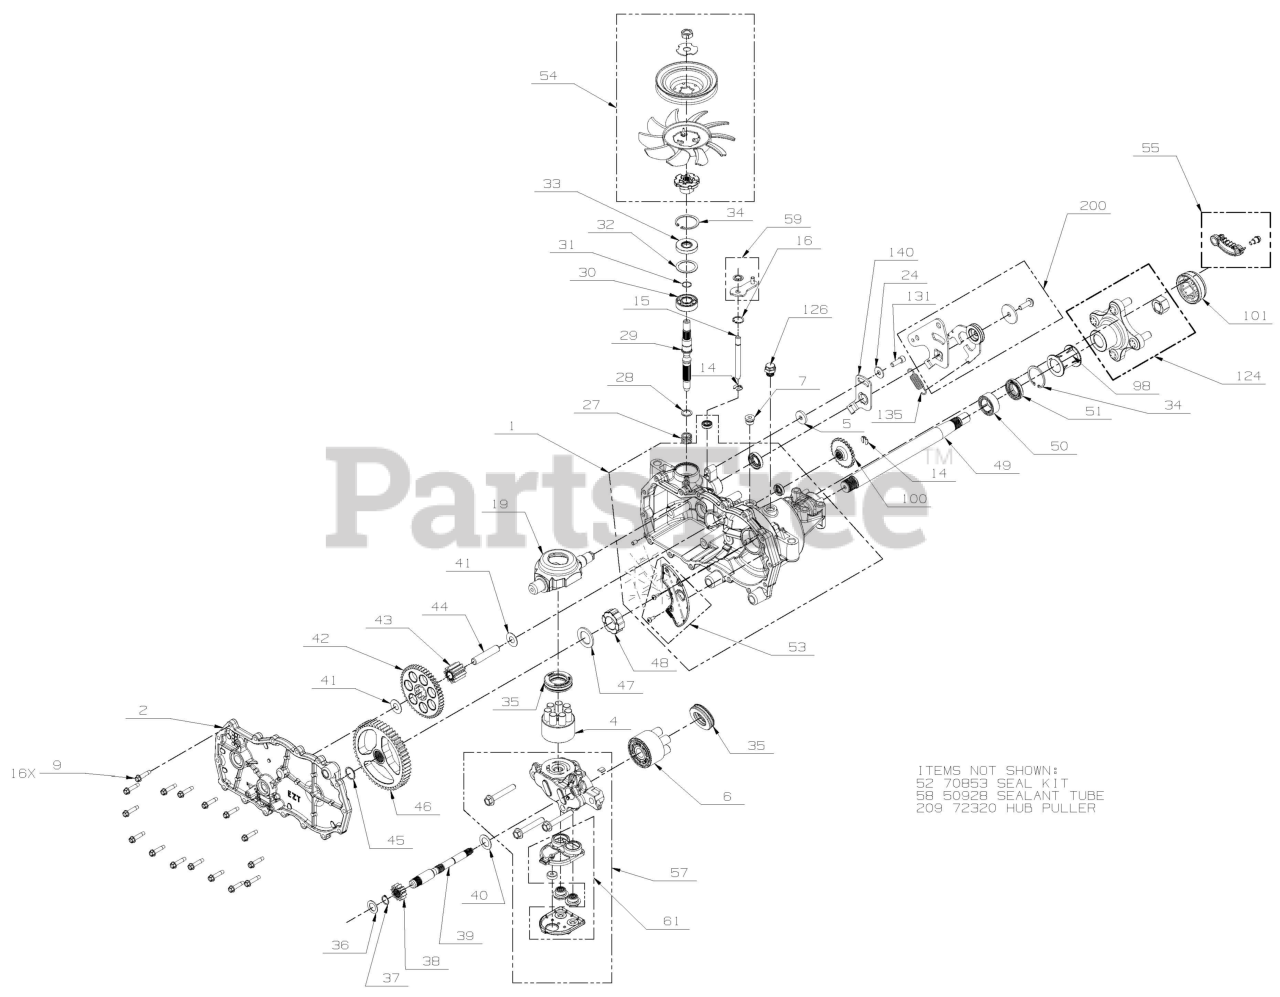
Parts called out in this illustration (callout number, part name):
1	ASSEMBLY, MAIN HOUSING
2	ASSEMBLY, SIDE HOUSING
4	ASSY, BLOCK 7 PISTON
6	KIT, 10 CC BLOCK
7	PLUG, 9/16-18 STR THREAD SOCKET HEAD
9	SCREW,HEX WASHER 1/4-20X1.125
14	RING. RETAINING
15	ROD, BYPASS
16	RING, RET .750
19	TRUNNION, SWASHPLATE
27	SPRING. BLOCK
28	WASHER. THRUST .59 X .79 X .04
29	SHAFT, INPUT
30	BRG, BALL 17X40X12
31	RING, RET WIRE .561 ID
32	WASHER 1.23X1.56X.04
33	SEAL, LIP 17X40X7
34	RING, RET 1.56 INT
35	BEARING. THRUST 30 X 52 X 13
36	WASHER .63X1.0X.05
37	RING, RET 62 EXT
39	SHAFT, MOTOR
40	WASHER .71 X 1.16 X .04
41	WASHER .5X1.0X.032
43	GEAR, 10T JACKSHAFT
44	JACK SHAFT (PIN)
47	WASHER, 1.018 X 1.571 X .105 FLAT
48	BUSHING, SLEEVE (INBOARD)
49	SHAFT, AXLE
52	KIT, SEALS AND RETAINING
53	KIT, EXPANSION PLATE RH
54	FAN PULLEY KIT 4.5X1.625
55	BRAKE ARM-LH, EZT
57	KIT, CENTER SECTION, W/FILTER - RH
58	SEALANT TUBE 10.1OZ.
59	KIT, BYPASS ARM
61	KIT, FILTER
100	DISC, COG BRAKE
101	CAP, AXLE
124	KIT, HUB 4 BOLT
126	ASSEMBLY, FITTING 9/16-18 BREATHER
131	KIT, RTN SCREWS
135	SPRING, HYDROGEAR P/N 51833
140	ARM, NEUTRAL RIGHT
200	KIT, RTN BIDIRECTIONAL
209	HUB PULLER 4 BLT HYDGEAR 71459
